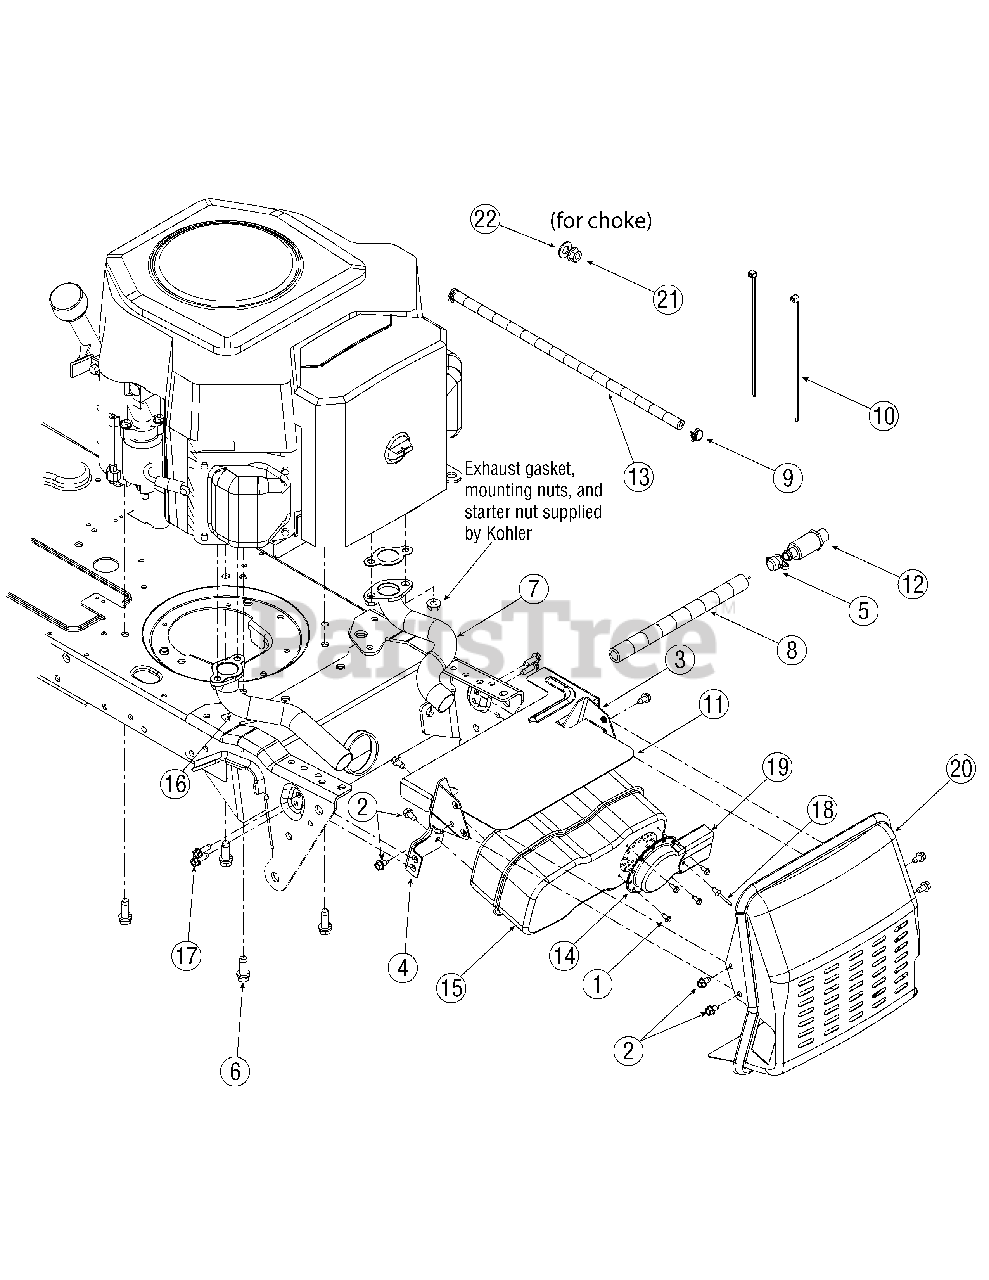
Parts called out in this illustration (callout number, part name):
1	AB Screw #8-18 x 0.5
2	TT Screw 1/4-20 x 0.5
6	TT Screw 3/8-16 x 1.00
7	Exhaust Pipe - LH
8	OIl Drain Extension Hose
9	Hose Clamp
10	Cable Tie
11	Twin Heat Shield
12	Oil Drain Valve
13	Fuel Line Hose
14	Muffler Deflector
15	Muffler
16	Exhaust Pipe - RH
17	Screw, 1/4-20, x .750
19	Long Muffler Deflector
21	Flange Lock Nut, 3/8-16
22	Flat Washer, .406 x .875 x .059
